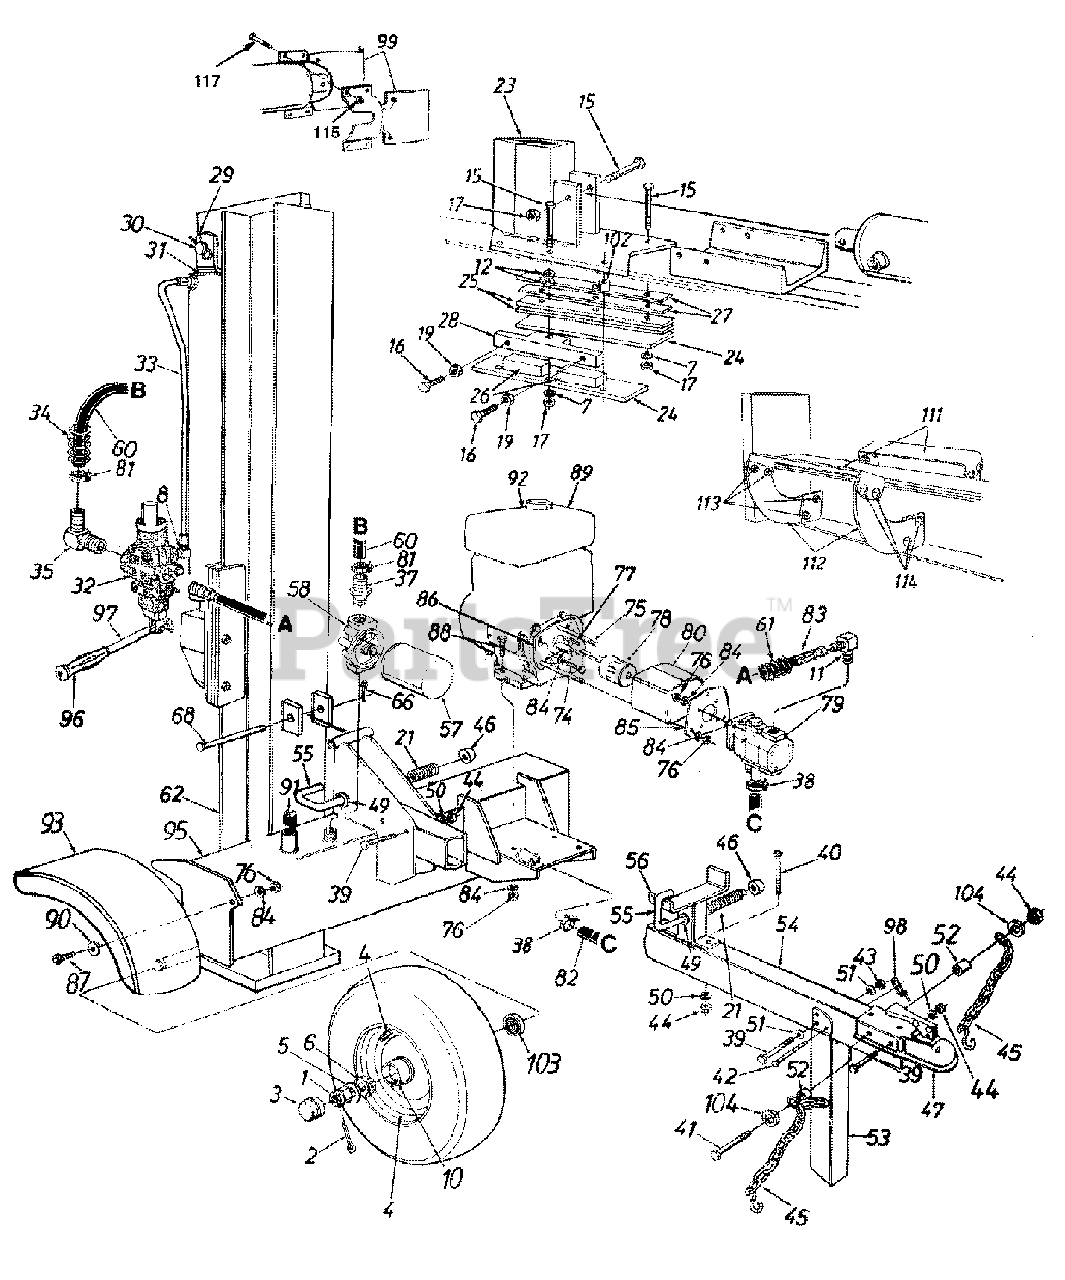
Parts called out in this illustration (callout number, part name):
1	Slotted Nut 3/4-16 Thd.
2	Cotter Pin 5/32" Dia.
3	Hub Cap
4	Wheel Ass'y. Comp.
4	Tire Only
4	Rim Only
4	Air Valve Only
5	Fl-Wash. .76" I.D. x 1.5" O.D.
6	Bearing Cone
7	L-Wash. 1/2" I.D.
8	90° Solid Male Adapter
10	Bearing Cup
11	90 degree Male Adapter
12	Fl-Wash. .531" I.D. x .94" O.D.
15	Hex Bolt 1/2-20 x 2.75" Lg.(Grade 8)
16	Hex Bolt 3/8-24 x 1.5" Lg.
17	Hex L-Nut 1/2-20 Thd.
19	Hex Jam Nut 3/8-24 Thd.(Grade 5)
21	Comp. Spring 4" Lg.
23	Wedge Ass'y.
27	Adjustable Gib Shim
29	Cotter Pin
30	Clevis Pin
31	Hydraulic Cylinder
32	Control Valve
33	Metal Pressure Tube
34	Hose Guard
35	Return Elbow
37	3/4" Hose Barb.
38	Hose Clamp 1.5" O.D.
39	Hex Bolt 3/8-16 x 3" Lg. (Grade 8)
40	Hex Bolt 3/8-16 x 4" Lg.
41	Hex Bolt 3/8-16 x 4.25" Lg.
42	Clevis Pin 5/16 x 2.5" Lg.
43	Hex L-Nut 3/8-16 Thd.
44	Hex Nut 3/8-16 Thd.
45	Chain-Tow Hitch
46	Push Cap
47	Hitch Coupler
49	Fl-Wash. .635" I.D. x .93" O.D.
50	L-Wash. 3/8" I.D.
51	Fl-Wash. .406" I.D. x .75" O.D.
52	Spacer .445" Lg.
53	Jack Stand
54	Tongue Tube
55	Locking Rod
57	Filter Element
58	Filter Head
60	Return Hose 3/4" I.D. x 44" Lg.
61	Hose Guard
68	Hinge Pin 1/2 x 4.8" Lg.
74	Hex Bolt 5/16-24 x .62" Lg.
75	Hex Bolt 5/16-24 x 5.25" Lg.
76	Hex Nut 5/16-24 Thd.
77	Sq.-Key 1/4" x 2" Lg.
78	Flexible Coupling
79	Gear Pump
80	Coupling Shield
81	Hose Clamp 5/8"
82	Suction Hose 1" I.D.
83	High Pressure Hydraulic Hose 48"
84	L-Wash. 5/16" I.D.
85	Rear Coupling Support Brkt.
86	Front Coupling Support Brkt.
87	Hex Bolt 5/16-24 x .75" Lg.
88	Hex Bolt 5/16-24 x 1.75" Lg.
89	Engine
90	Fl-Wash. .344" I.D. x .875" O.D.
91	L-Vent Pipe Plug
92	Spark Plug Boot
93	Fender
95	Frame Weldment
97	Control Handle
98	Spring Pin
99	Dislodger
102	Spacer 1/2" I.D. x .86" Lg.
103	Bearing Seal Only
104	Fl-Wash. 3/8" I.D. x .87" O.D.
111	Log Cradle
112	Cradle Support Brkt.
113	Flanged Lock Nut 3/8-16 Thd.
114	Carriage Bolt 3/8-16 x 1" Lg.
115	Hex L-Nut 3/8-16 Thd.
117	Hex Bolt 3/8-16 x 2.0" Lg. (Gr. 5)
